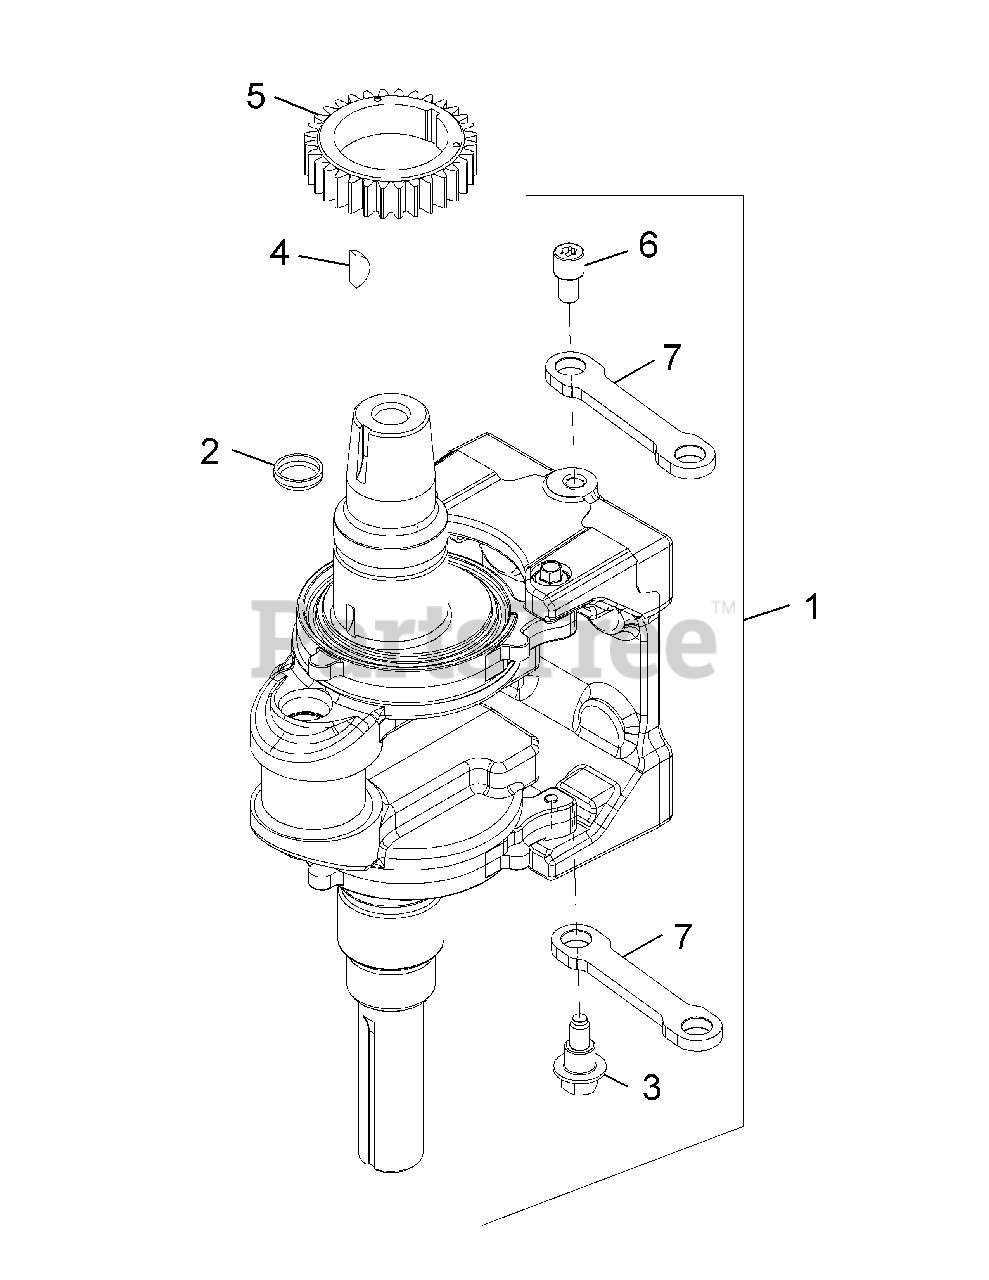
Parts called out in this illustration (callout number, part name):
1	Crankshaft Assembly Kit
3	Shoulder Screw
4	Key, 3/16 X 5/8
5	Crankshaft Gear
6	Link Pivot Screw
7	Balance Weight Linkage
